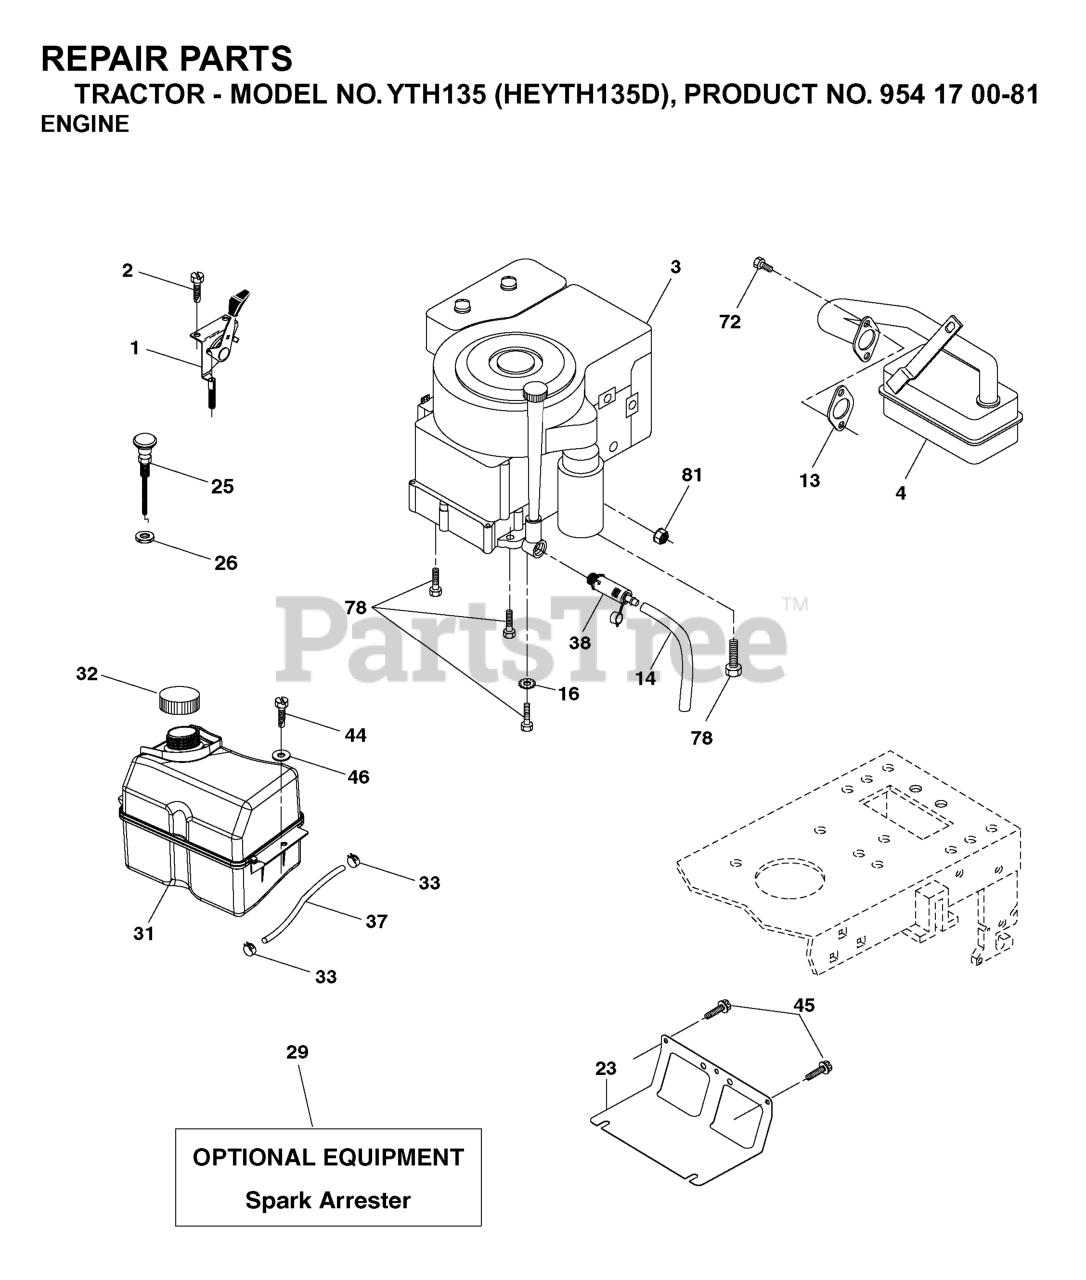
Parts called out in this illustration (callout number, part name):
1	CONTROL.THROTTLE/CHOKE.BLACK
2	SCREW
4	MUFFLER.LT.BRIGGS.14HP.IC/OHV
13	REPL BY 532 27 22-93
14	TUBE, DRAIN OIL ASM.
16	LOCKWASHER
23	SHIELD.BROWNING.DBR.GUARD
26	Nut Keps 3/8 - 24 UNF
29	KIT.SPARK ARRESTOR 794945 B&S
31	TANK FUEL
32	FUEL CAP
33	HOSE CLAMP
37	LINE.FUEL.20
38	PLUG DRAIN OIL EASY
44	SCREW HEXWSHR 1/4-20X3/4
45	SCREW, 3/8-16X3/4
72	SCREW.SOCKET.HEAD.5/16-18
78	SCREW.3/8-16
81	NUT
